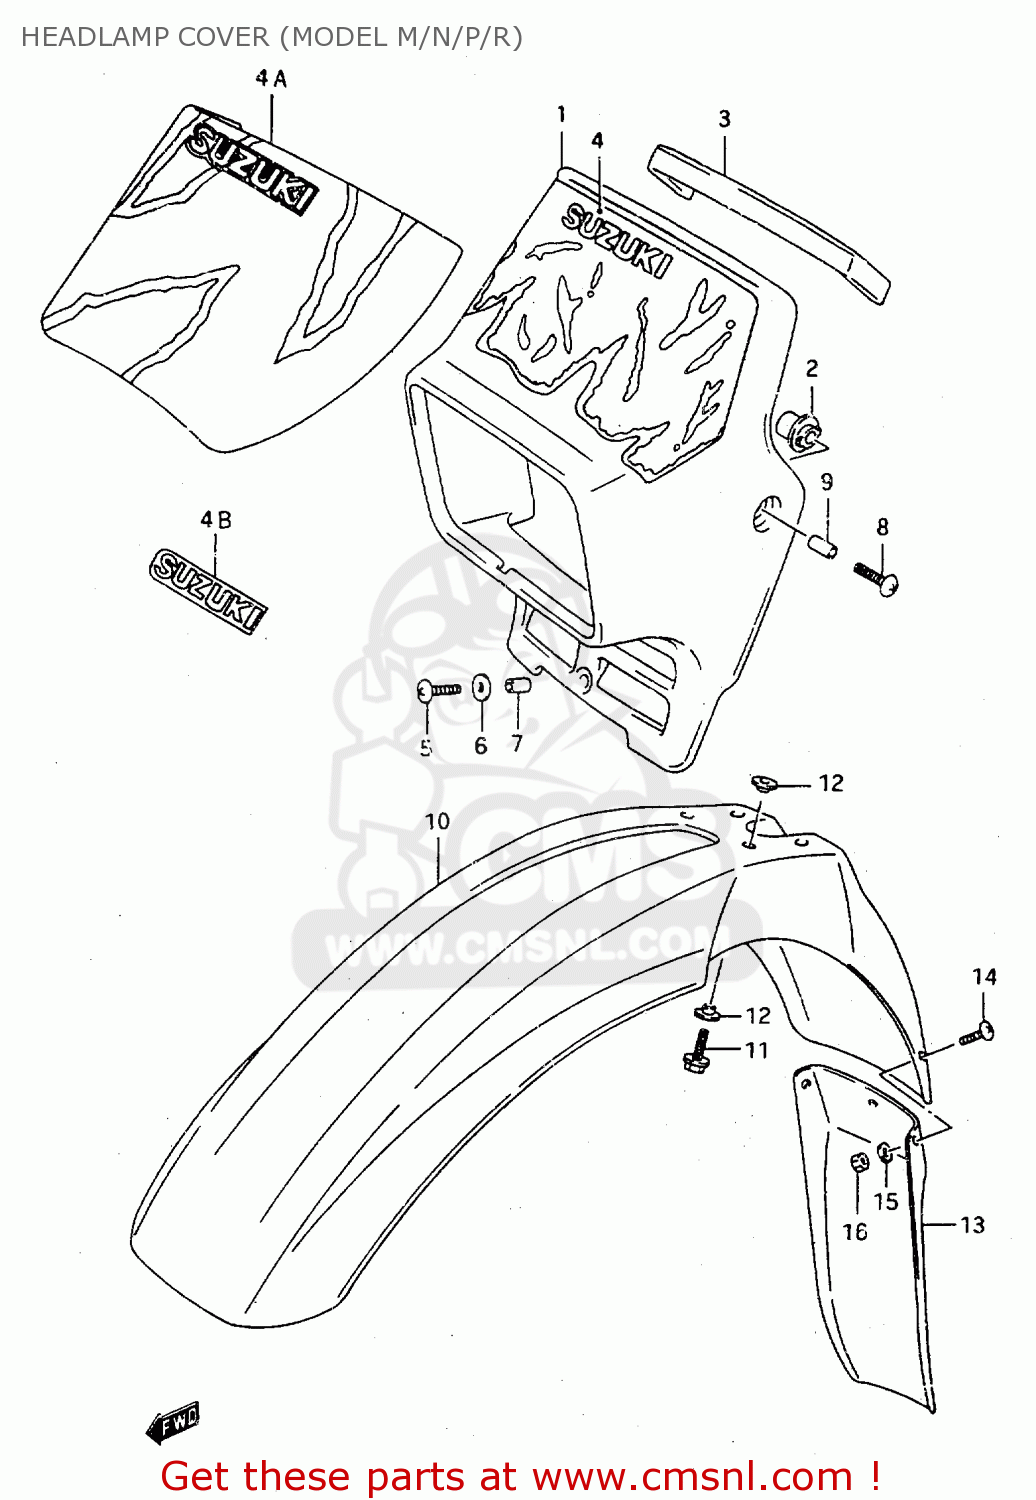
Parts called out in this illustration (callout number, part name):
1	COVER,HEADLAMP
2	SPACER,HEAD LAMP COVER
3	CUSHION,HEAD LAMP HOUSING
4	TAPE, HEADLAMP COVER
4A	TAPE, HEADLAMP COVER
4B	EMBLEM,RR FENDER
5	SCREW
6	WASHER (5.5X14X1.2)
7	SPACER (6.1X8X12)
8	SCREW
9	SPACER (6.1X8X15.5)
10	FENDER, FRONT (BLUE)
11	BOLT
12	WASHER
13	MUD FLAP, FRONT FENDER
14	SCREW(5X10)
15	WASHER
16	NUT
21	SCREW(5X10)
22	WASHER
23	NUT 5MM
